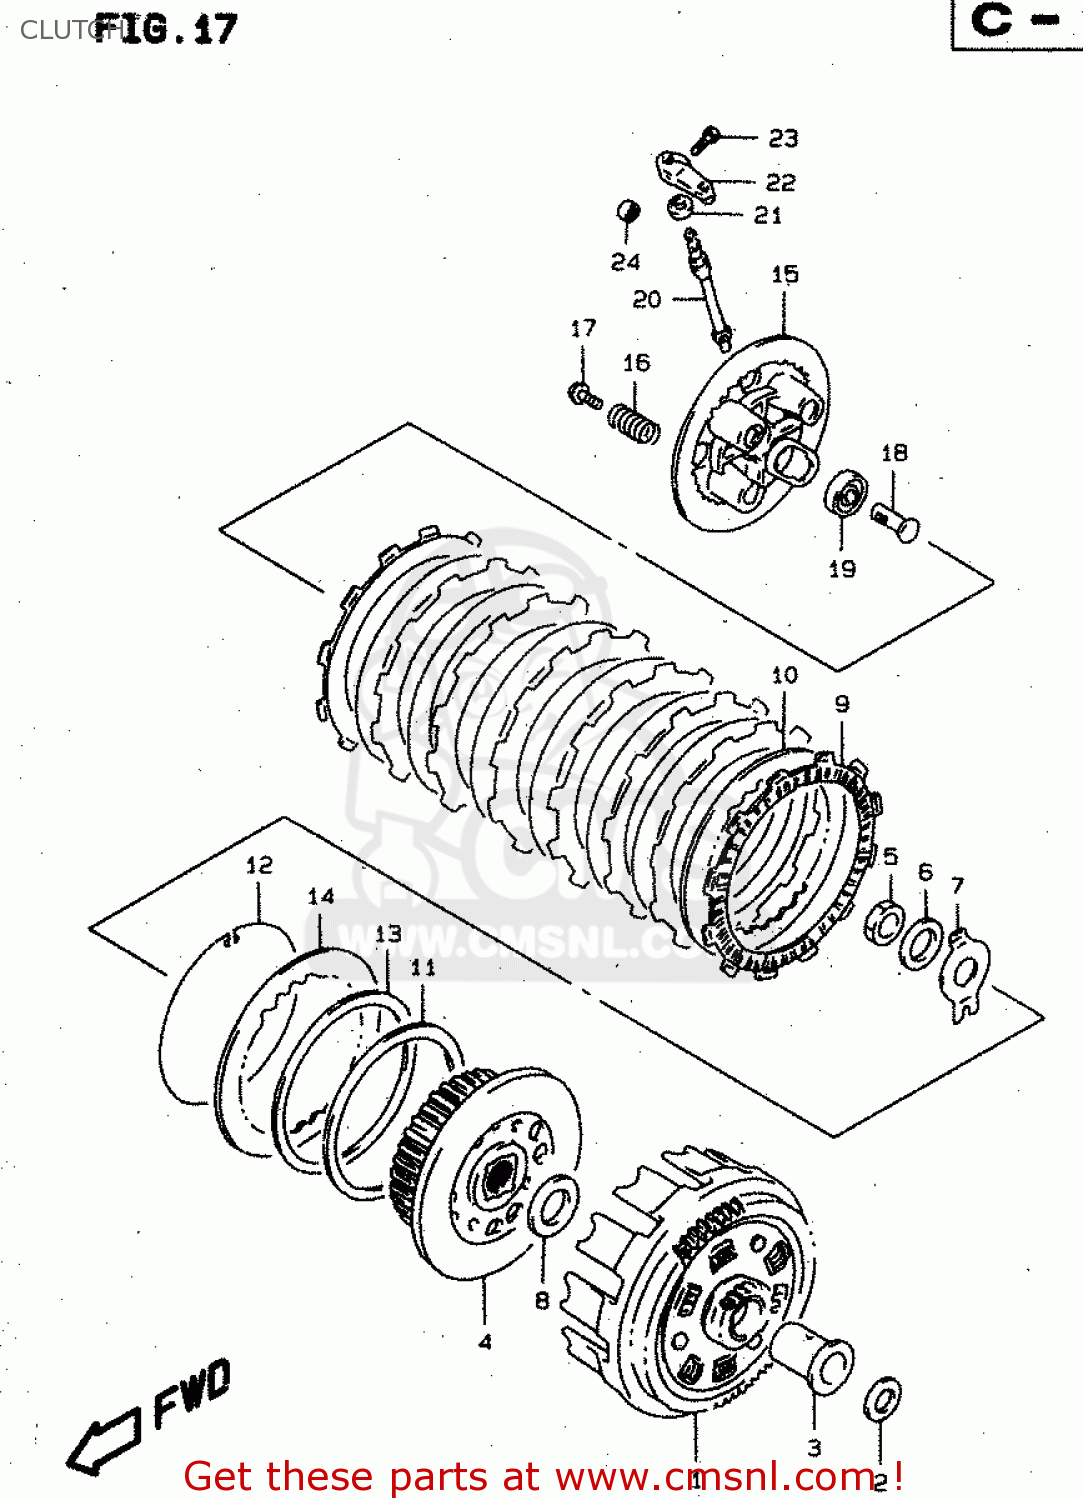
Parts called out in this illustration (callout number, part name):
1	GEAR ASSY,PRI DRIVEN
2	WASHER(22X32X3)
3	SPACER,PRIMARY DRIVEN GEAR
4	HUB,CLUTCH SLEEVE
5	NUT
6	WASHER
7	WASHER
8	WASHER(22X44X2)
9	PLATE,CLUTCH D
10	PLATE,CLUTCH DRIVEN NO.1 (NAS)
11	SEAT,WAVE WASHER
12	RING,STOPPER
13	WASHER
14	PLATE,CLUTCH DRIVEN (NAS)
15	DISC,CLUTCH PRESSURE
16	SPRING
17	BOLT(6X16)
18	RACK,CLUTCH RELEASE
19	BEARING
20	PINION,CLUTCH RELEASE
21	SEAL,OIL(10X17X5)
22	ARM,CLUTCH RELEASE
23	BOLT
24	BEARING(12X16X10)
